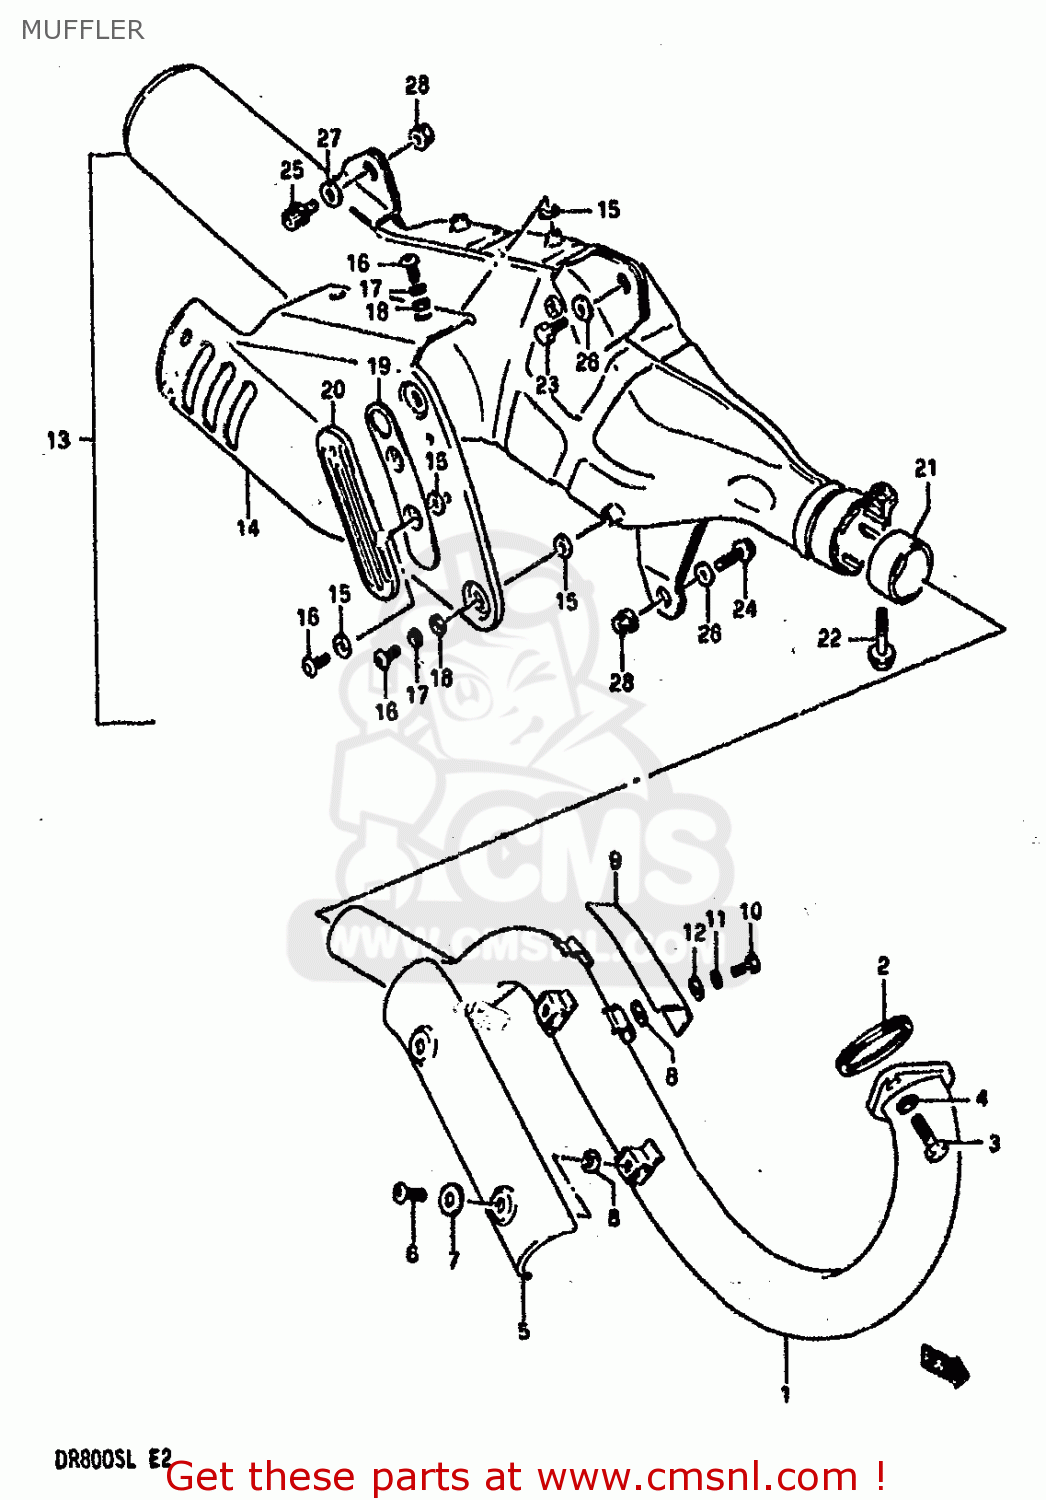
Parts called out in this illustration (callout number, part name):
1	PIPE,EXHAUST
2	GASKET,EXHAUST PIPE (NAS)
3	BOLT
4	WASHER,LOCK,8.
5	COVER,EXHAUST PIPE
6	SCREW
7	WASHER
8	GASKET (NAS)
9	PLATE,HEAT GUARD
10	BOLT
11	WASHER,LOCK
12	WASHER
13	MUFFLER ASSY
14	COVER,MUFFLER
15	GASKET (NAS)
16	SCREW
17	WASHER,LOCK
18	WASHER(6.5X18X1)
19	GUARD,MUFFLER COVER
20	COVER,MUFFLER COVER GUARD
21	CONNECTOR,MUFFLER
22	BOLT 8X40
23	BOLT
24	BOLT
25	BOLT
26	WASHER (8.5X19X2.3)
27	WASHER(8.2X23X3.2)
28	NUT
